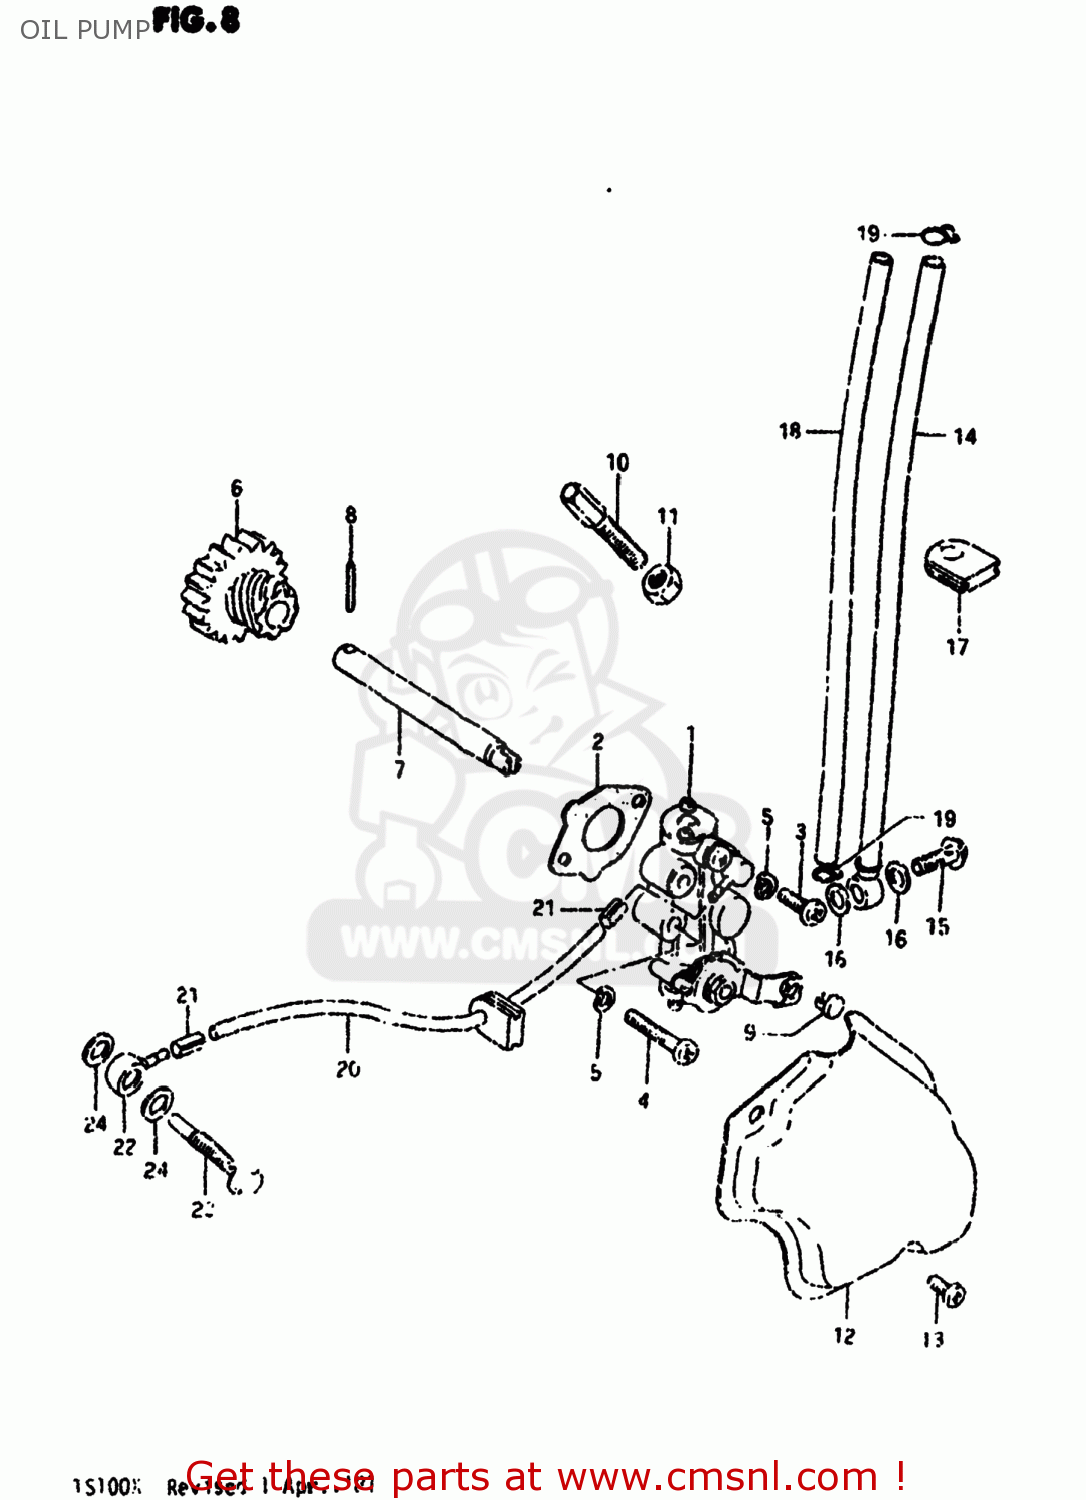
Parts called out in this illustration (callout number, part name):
1	PUMP ASSY,OIL
2	GASKET,OIL PUMP (NAS)
3	SCREW
4	SCREW
5	LOCK WASHER
6	GEAR,OIL PUMP DRIVE
7	SHAFT,OIL PUMP DRIVE
8	PIN(2.5X19.8)
9	TERMINAL,CABLE
10	BOLT
11	NUT
12	CAP,OIL PUMP INSPECTION
13	SCREW
14	HOSE,OIL NO.1
15	UNION BOLT
16	GASKET(6.2X11X1).2 (NAS)
17	GROMMET
18	HOSE
19	CLIP
20	HOSE,OIL NO.2
21	CLIP
22	UNION
23	UNION
24	GASKET(6.2X11X1).2 (NAS)
